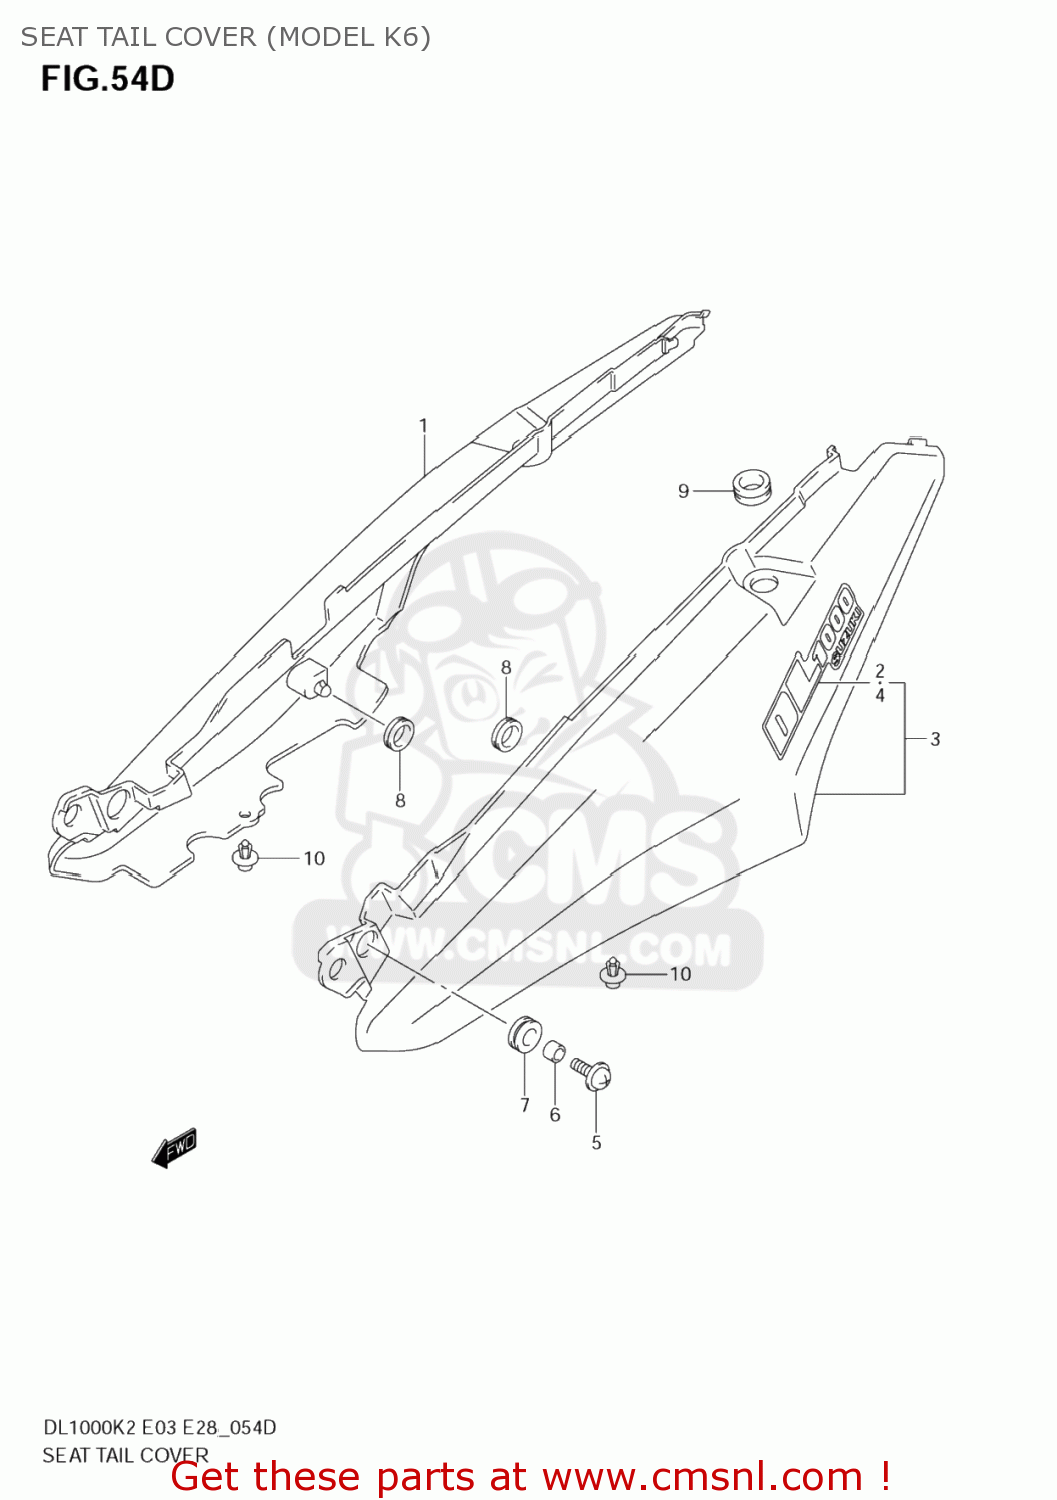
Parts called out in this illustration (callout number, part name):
1	COVER,SEAT TAIL,R(BLACK)
2	EMBLEM,SEAT TAIL COVER
3	COVER,SEAT TAIL,L(BLACK)
4	EMBLEM,SEAT TAIL COVER
5	SCREW(6X20)
6	SPACER(6.5X12X9)
7	CUSHION
8	CUSHION
9	CUSHION
10	CLIP(BLACK)
